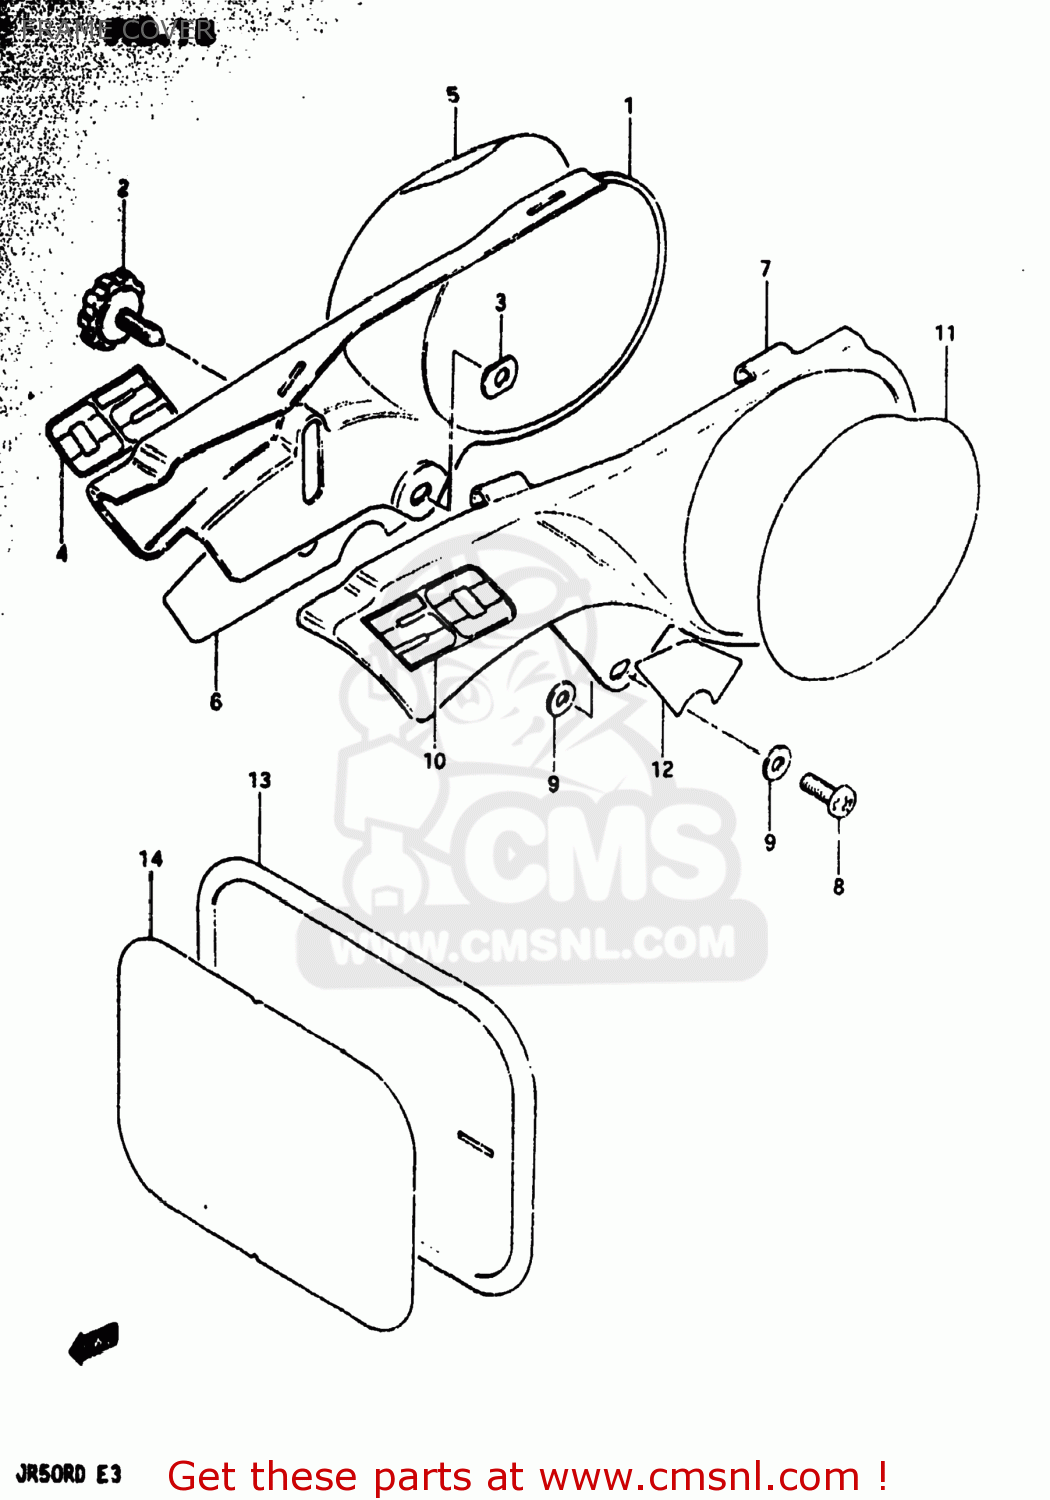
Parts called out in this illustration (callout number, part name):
1	COVER,FRAME,RIGHT
2	KNOB,FRAME COVER,R
3	NUT
4	EMBLEM
5	EMBLEM
6	EMBLEM,FRAME COVER,R LWR
7	COVER,FRAME,LEFT
8	SCREW 6X12
9	WASHER
10	EMBLEM,FRAME COVER
11	EMBLEM,FRAME COVER
12	EMBLEM,FRAME COVER,L LWR
13	PLATE,NUMBER,FRONT
14	EMBLEM,FRONT NUMBER PLATE
